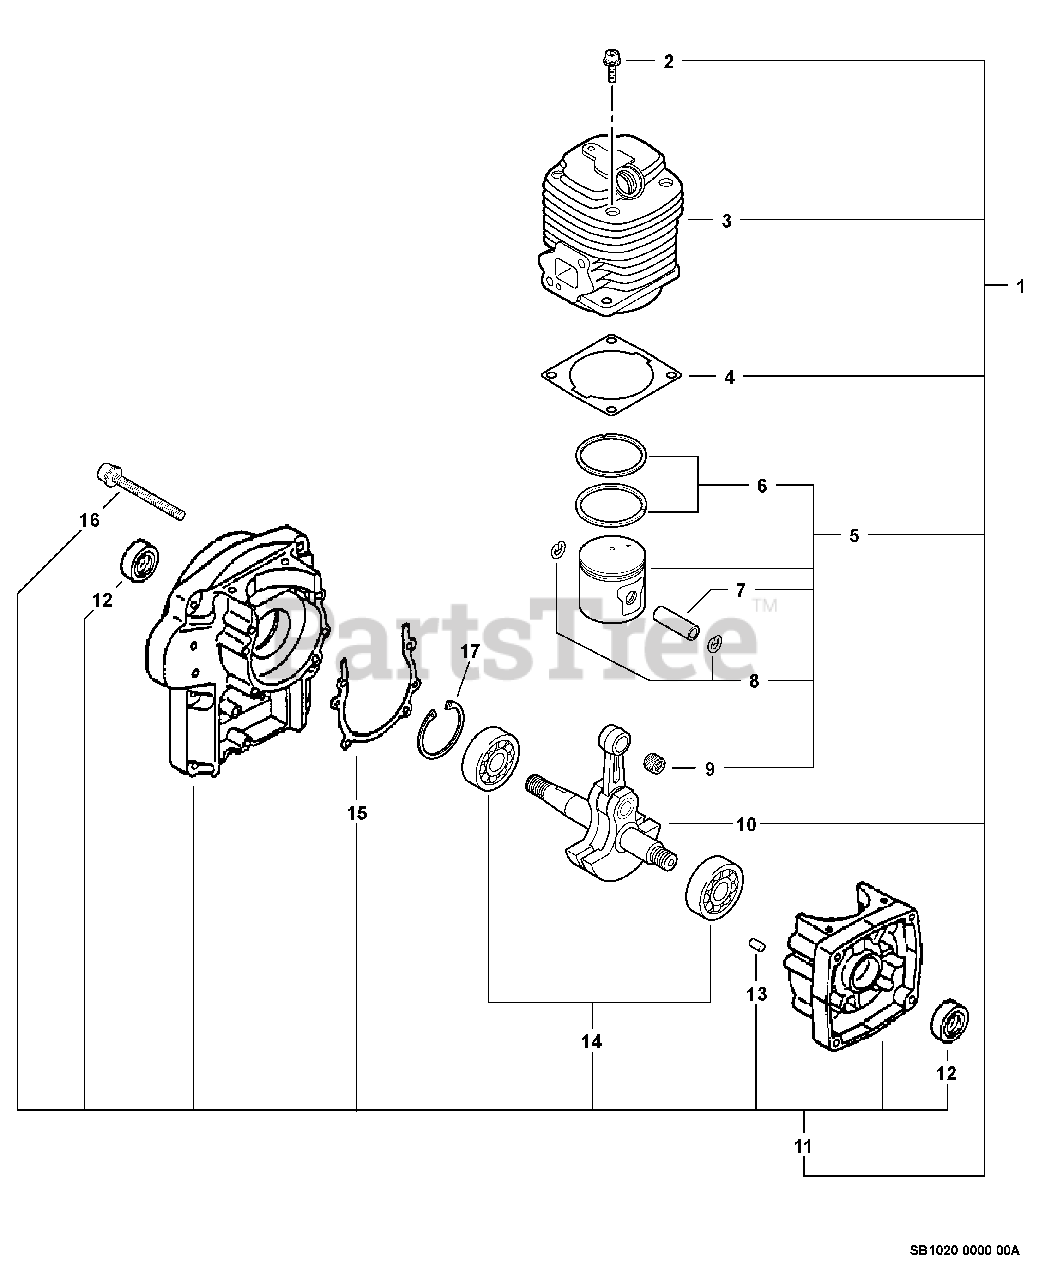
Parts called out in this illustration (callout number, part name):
1	SHORT BLOCK -- SB1020
2	SCREW - 5X22
3	CYLINDER
4	GASKET, CYLINDER
5	PISTON KIT
6	RING, PISTON
7	PIN, PISTON
8	RING, RETAINING - 8
9	BEARING, NEEDLE
10	CRANKSHAFT ASSY
11	CRANKCASE KIT
12	SEAL, OIL
13	PIN - LOCATING
14	BEARING, BALL - 6202
15	GASKET, CRANKCASE
16	SCREW - 5X40
17	RING, RETAINING - 35
